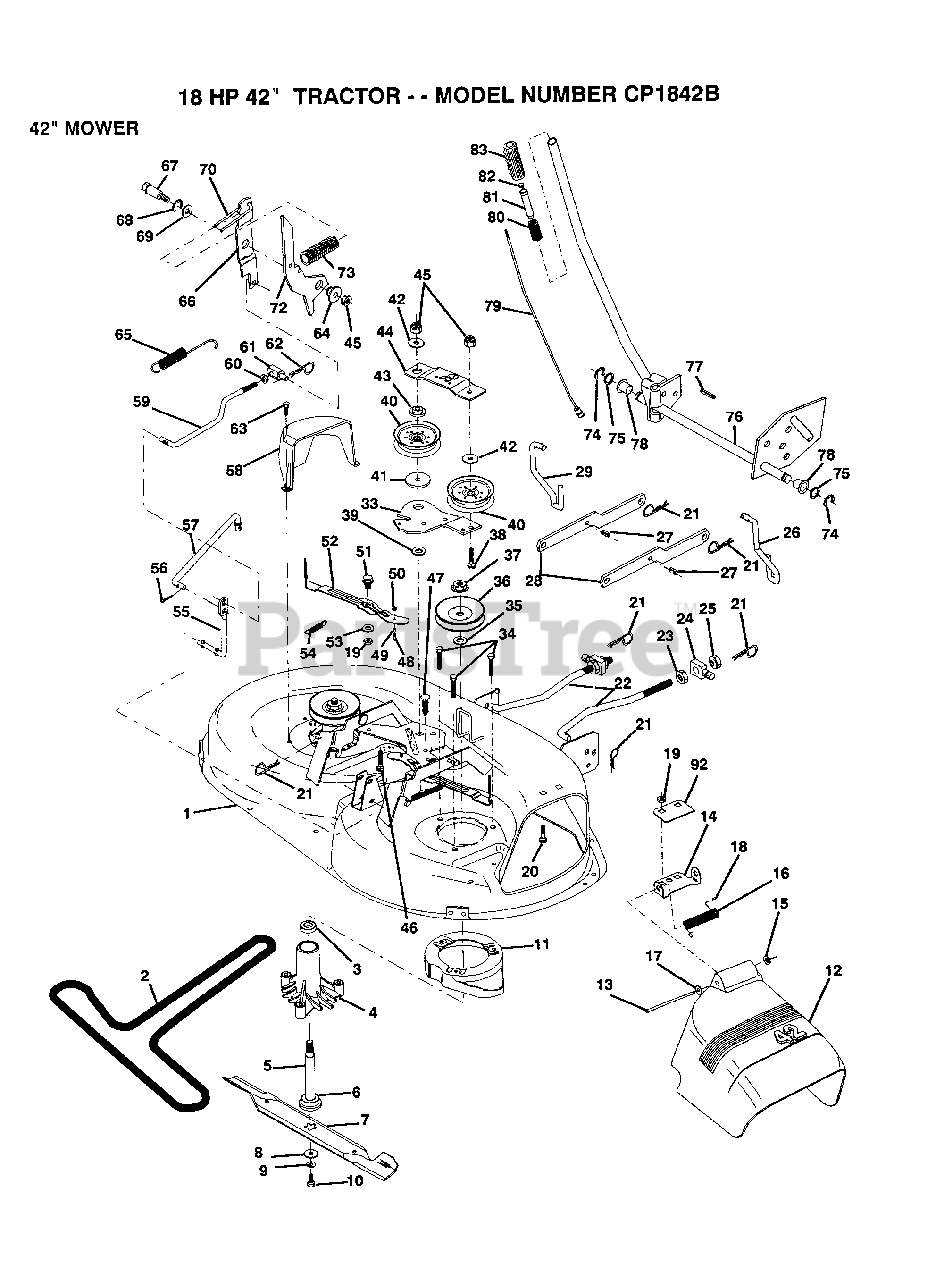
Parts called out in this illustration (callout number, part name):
2	BELT-V.92.4.MWR
3	BEARING
4	HSG ASM MANDREL
6	BEARING.BALL
8	WASHER BLADE
10	BLADE BOLT
12	DEFLECTOR.SHIELD
13	HINGE ROD
14	HINGE ROD
14	DEFLECTOR BRKT
15	NUT PUSH M
16	SPRING TORSION
17	WASHER
18	CAP-SLEEVE LT
20	BOLT
22	LINK.FRONT
23	NUT
24	TRUNION
25	NUT.LK.W/WSH.1/2.
26	LIFT LINK RH
27	"PIN,SPRING"
28	SUSP ARM ASM REAR
29	LINK LIFT LH
33	IDLER ARM
35	WASHER
38	BOLT
39	HARDENED WASHER
40	FLAT IDLER PULLEY
41	SPACER RETAINER
42	WASHER GT
43	RETAINER SPACER
44	IDLER ARM STIFF
46	BOLT CARRIAGE
47	XMAS TREE FASTNER
48	SHOULDER BOLT
50	LOCKNUT
52	BRAKE PAD ARM ASM
53	HARD SMALL WASHER
54	SPRING EXTENSION
55	PIVOT ROD
57	CLUTCH ROD SECOND
60	NUT
61	TRUNION
62	RETAINER M
63	SCREW LT
64	BUSHING
65	RETURN SPRING
66	CLUTCH ARM SECOND
67	SHOULDER BOLT
68	RING
69	WASHER
70	SPRING KEEPER
75	WASHER
76	LIFT SHAFT ASM
77	PIN-GROOVE LT
78	NYLON BEARING
83	GRIP
92	STIFFENER BRKT
